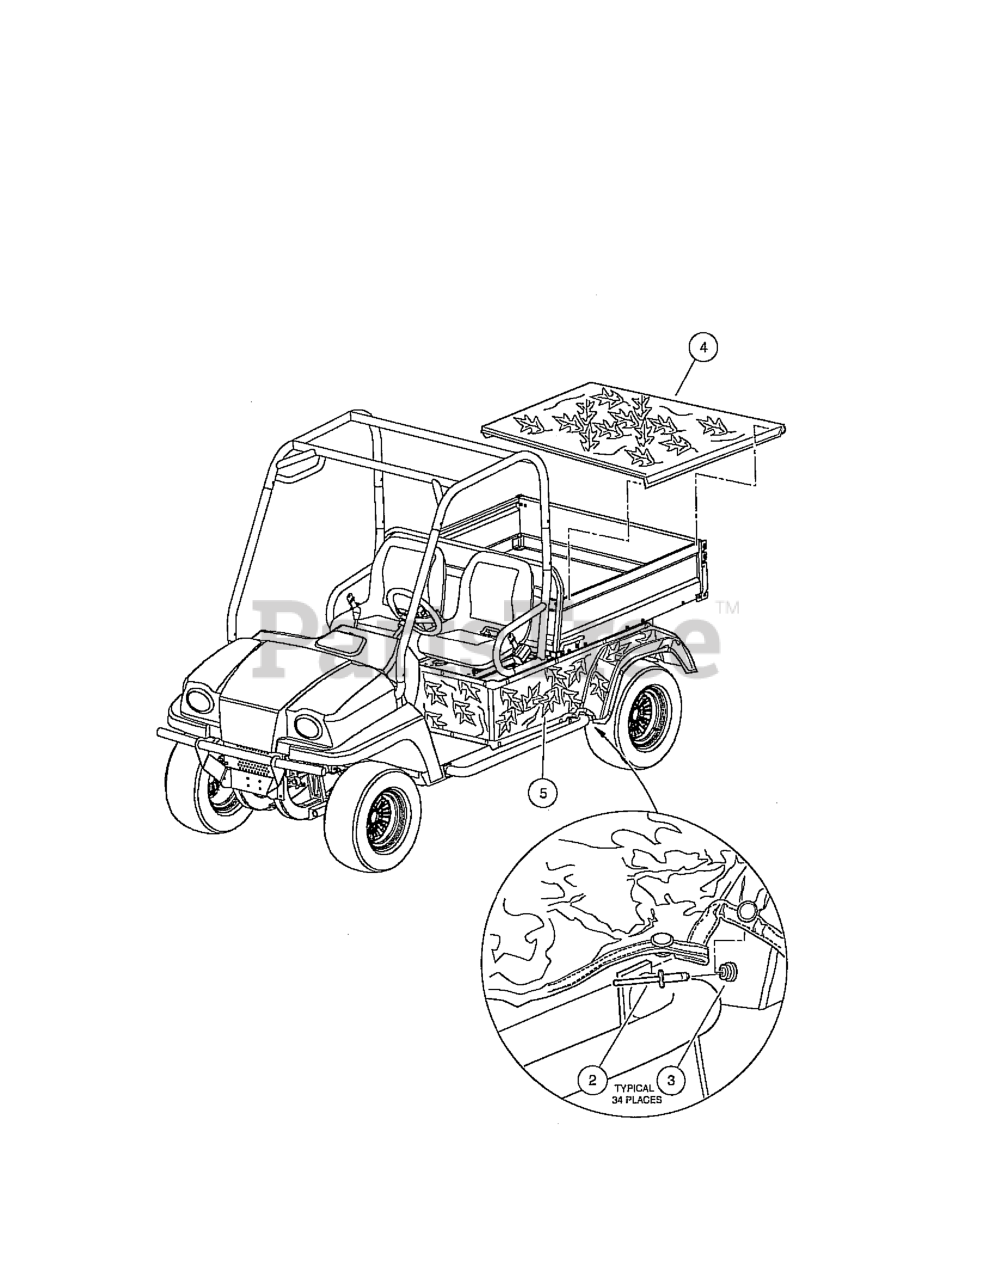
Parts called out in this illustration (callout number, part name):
1	KIT, CAMO COVER, 4X4
4	Cover, Camouflage Cargo Box
5	AWD REAR BODY WRAP FOREST FLR
